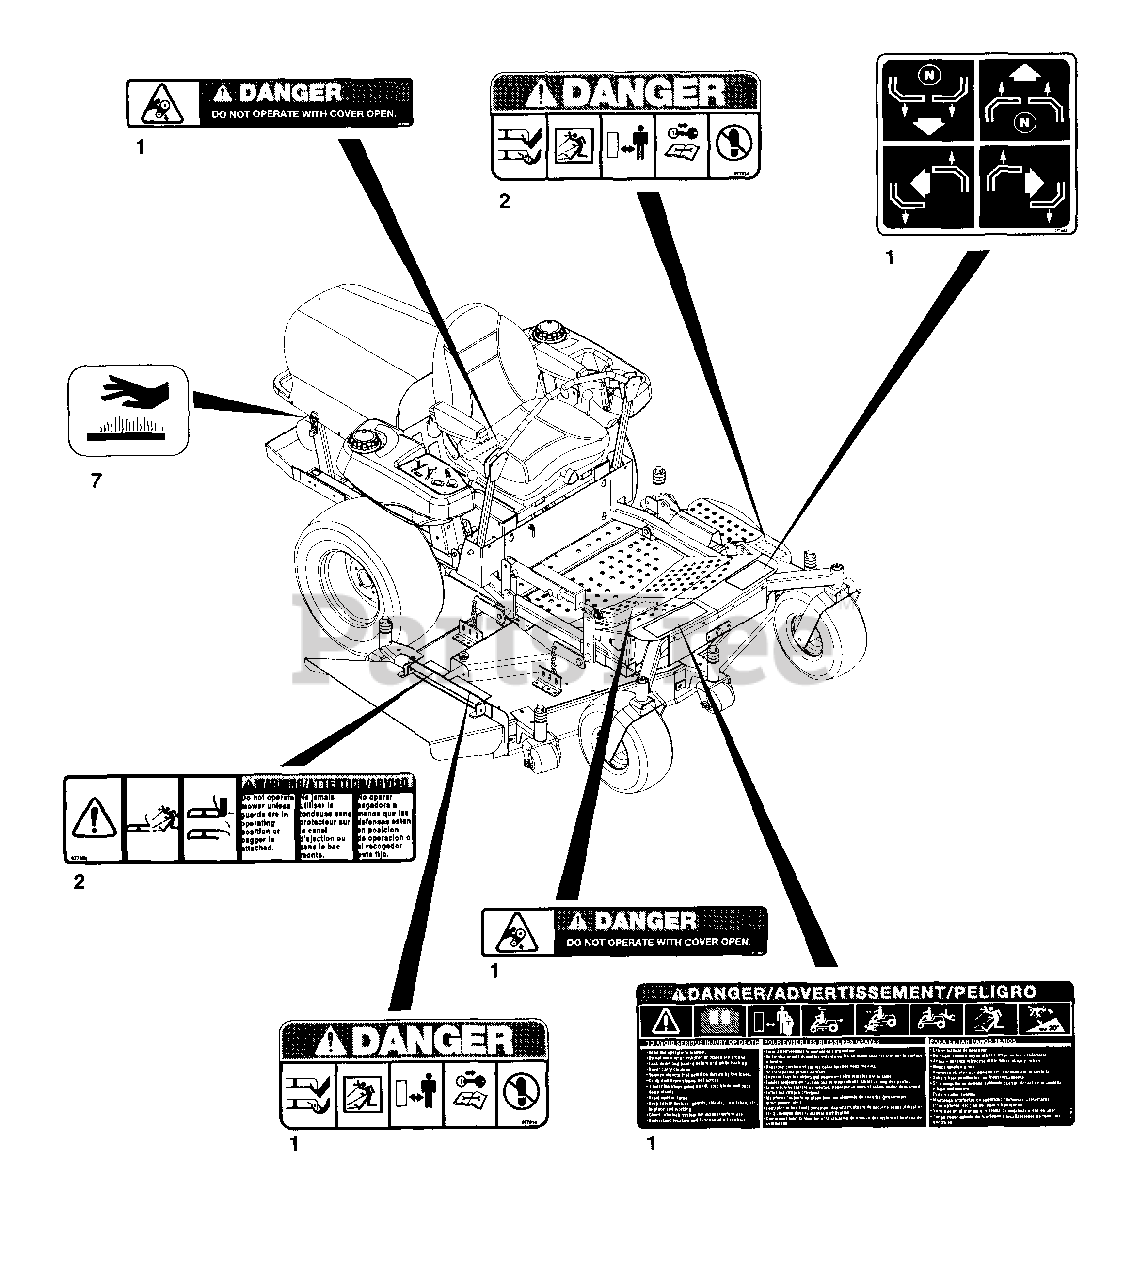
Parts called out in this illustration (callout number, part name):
1	Decal Set PM260Z
2	Decal Set Mower Decks
2	Decal-PM 250Z Logo
7	Decal-Hot Surface
